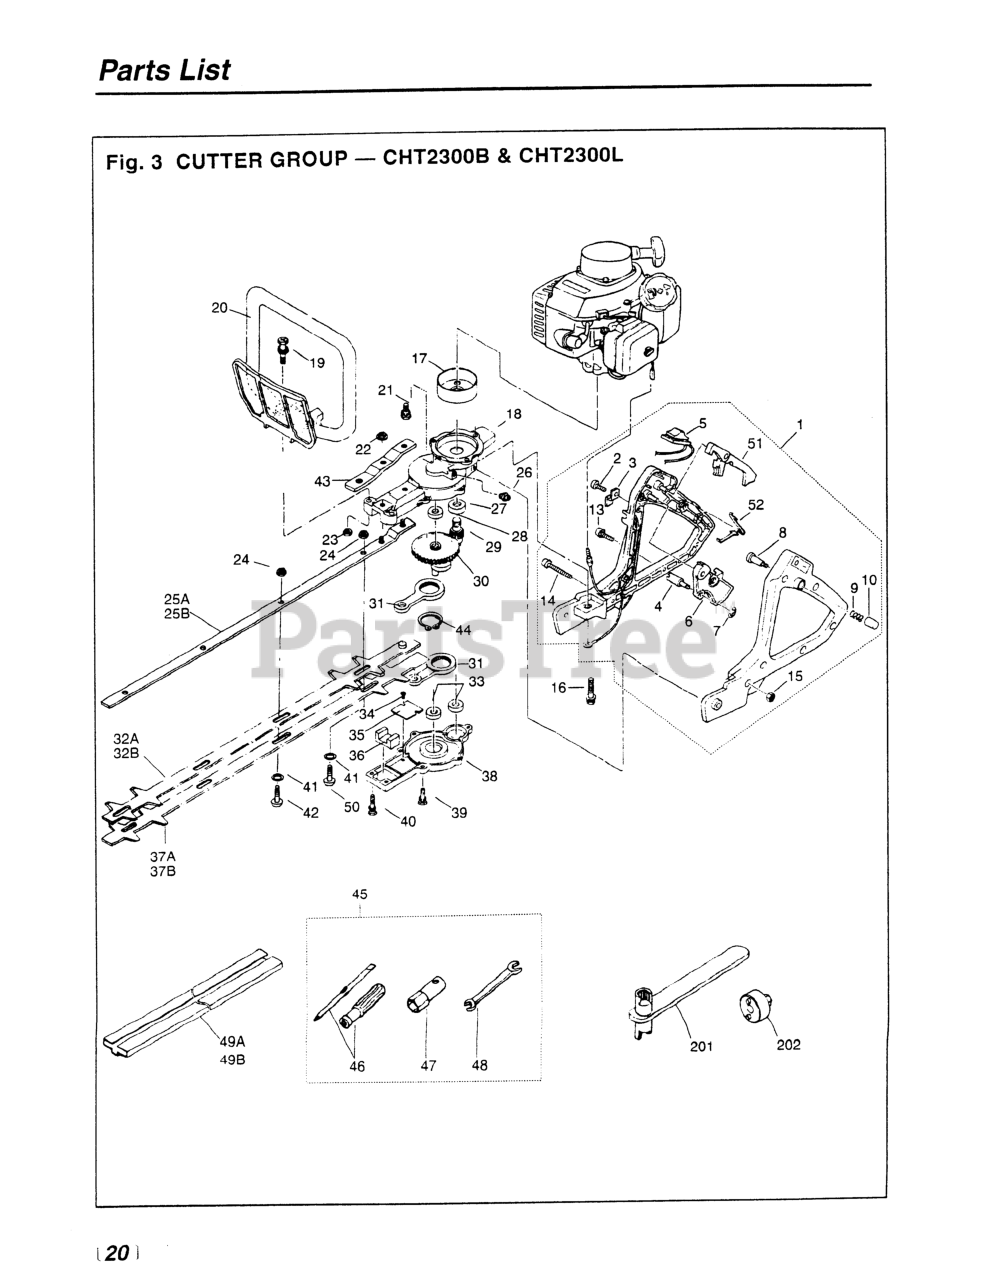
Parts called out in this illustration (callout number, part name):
1	HANDLE, REAR ASSY (RPL 3873-)
2	SCREW, M4 x 10
3	PLATE
4	END, CABLE
5	SWITCH
6	LEVER, THROTTLE (RPLS -13220)
7	RING, SNAP
9	SPRING
10	CAP, PIN
13	NUT, M6 X 4
14	BOLT, M6 X 50
15	NUT, M6 X 5
16	BOLT, M6 X 40
17	DRUM, CLUTCH
18	CASE, MIDDLE (RPLS -11110)
20	HANDLE (RPLS -12101)
21	BOLT, M6 X 14
22	NUT
23	NUT, M6 X 5
24	NUT, M6
25B	PLATE, GUIDE (RPLS -11611) 30
26	FITTING, GREASE
27	BEARING
28	BEARING
29	PINION
30	GEAR COMPLETE
31	ROD
32B	BLADE, UPPER DOUBLE 30
33	BEARING
34	SCREW, M3 x 5
35	PLATE
36	FELT
37B	BLADE, LOWER DOUBLE 30
38	CASE, LOWER
39	BOLT, M5 x 16
40	BOLT, M5 X 20
43	PLATE (RPLS 3880-11130)
44	RING, SNAP, M25 X 1.2
45	TOOL SET
46	SCREWDRIVER
47	SOCKET, HEX, 3/4
48	SPANNER, 8 X 10 (RPLS 2540- )
49B	COVER, BLADE (30
202	WRENCH (TOOL)
NI	SCREW, M4 X 16
NI	SCREW, M4 x 30
